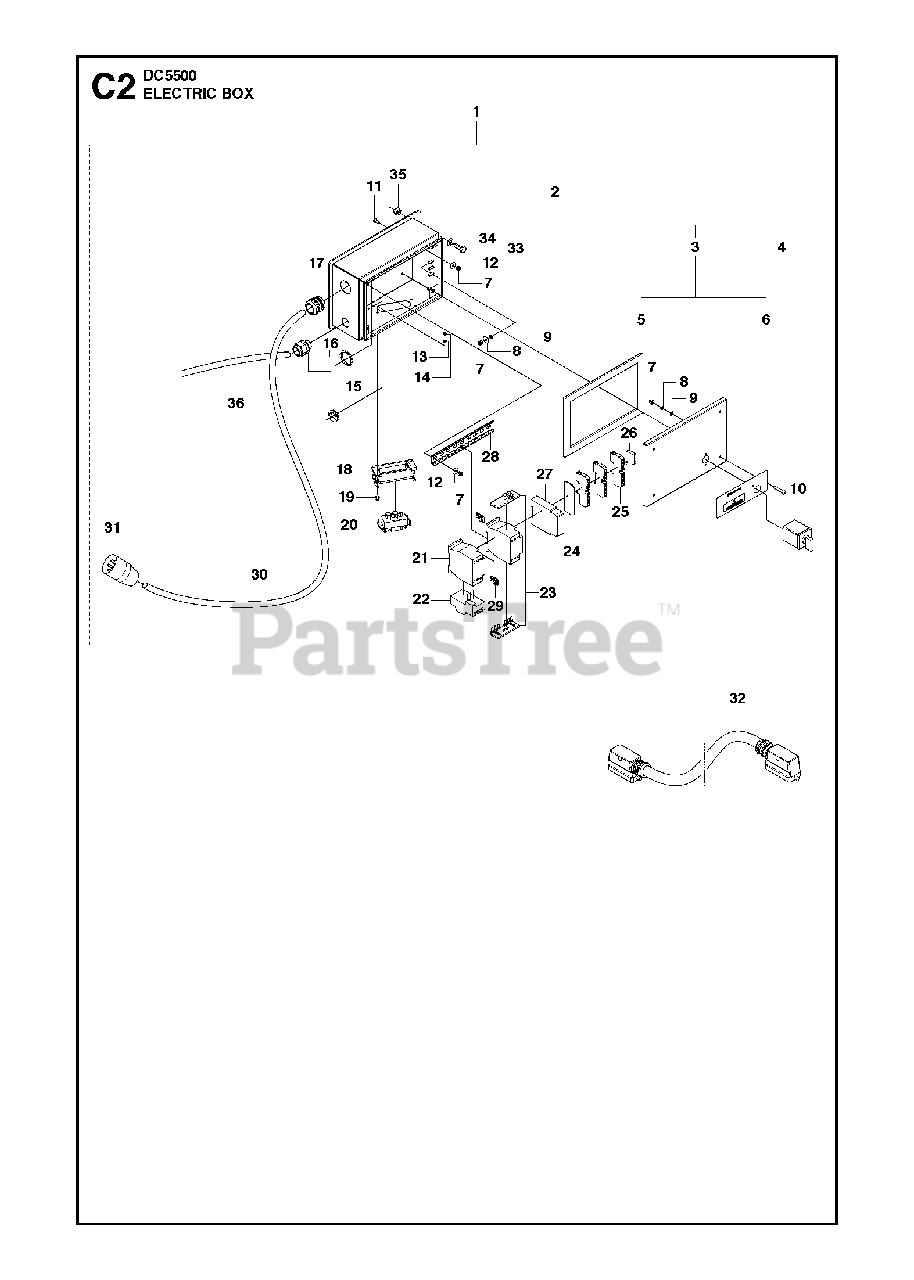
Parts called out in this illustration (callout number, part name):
7	HEXAGON LOCKING NUT
14	HEXAGON LOCKING NUT
19	SCREW CRPANM
34	WASHER
35	HEXAGON LOCKING NUT
